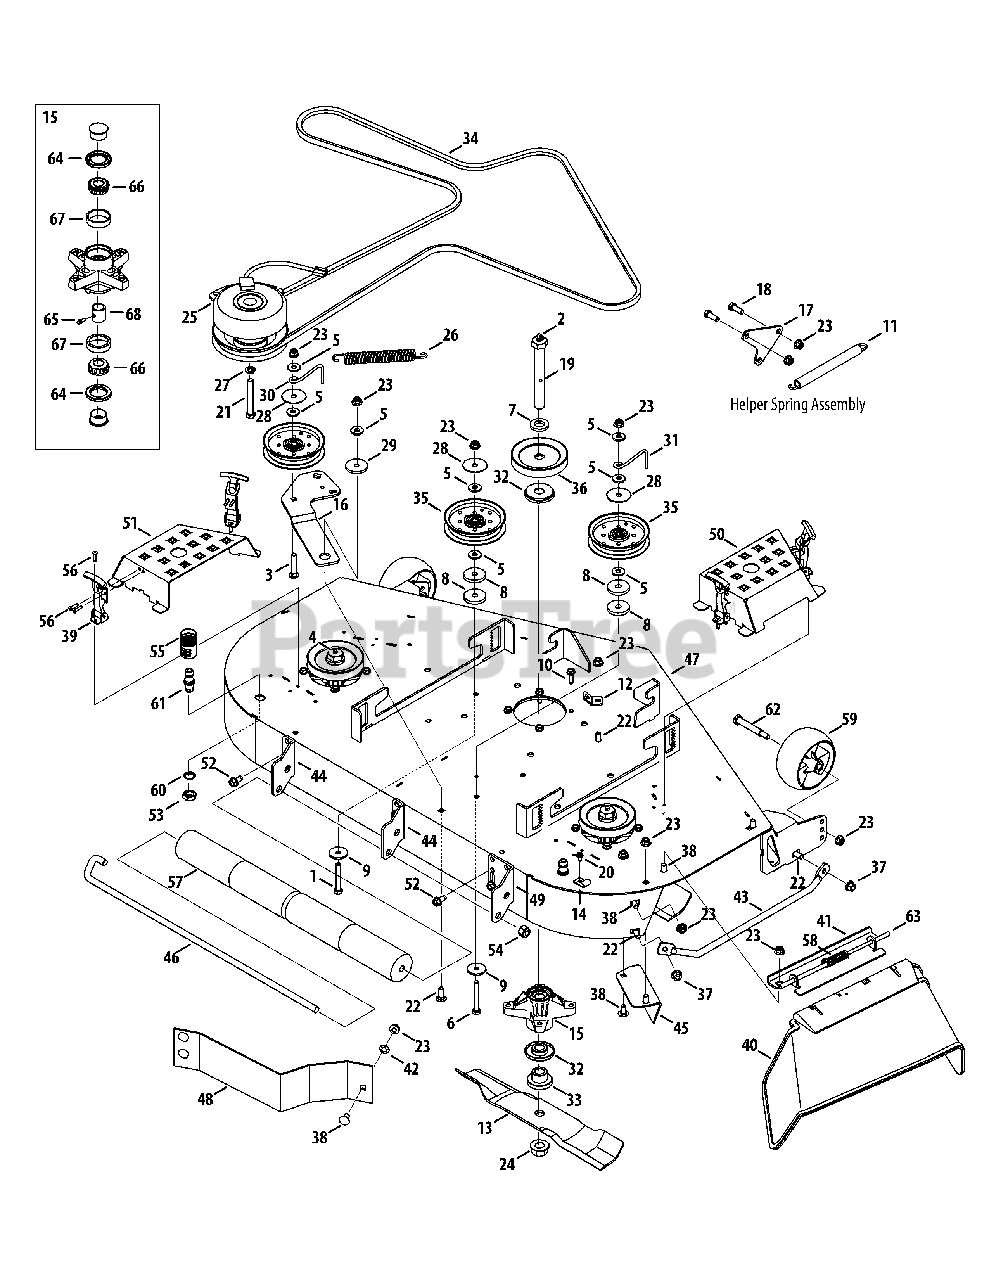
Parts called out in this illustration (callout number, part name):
1	Hex Screw, 3/8-16 x 2.50
2	Grease Fitting, 1/4-28 x .788
3	Carriage Bolt, 3/8-16 x 2.00
4	Straight Grease Fitting, 1/4-28
5	Washer, .406 x 1.00 x .105
6	Hex Screw, 3/8-16 x 2.75
7	Spacer, .812 x 1.47 x .218
8	Washer, .438 x 1.75 x .250
9	Washer, .390 x 1.50 x .122
10	Flange Hex TT Screw, 5/16-18 x 1.00
11	Hook Ext. Spring, .75 x 7.89 x .14
12	45-Degree Spring Mount Bracket
13	Blade, Hi-Lift, 17.0
14	Retainer Hook Bracket
15	Deck Spindle Assembly
18	Hex Screw, 3/8-16 x 1.00
19	Hex Screw, 3/4-16 x 6.00
20	Hex Washer TT Screw, 1/4-20 x .500
21	Hex Screw, 7/16-20 x 3.25
22	Carriage Bolt, 3/8-16 x 1.00
23	Flange Lock Nut, 3/8-16
24	Flange Lock Nut, 3/4-16
25	Electric PTO Clutch
26	Extension Spring, .91 x 7.33
27	Lock Washer, 7/16
28	Flat Washer, .406 x 1.92 x .060
29	Shoulder Spacer, .884 x .190
30	Belt Keeper Rod
31	Belt Keeper Rod
32	Deck Spindle Spacer
33	Spindle Spacer, .76 x 2.0 x 1.1
34	Hi-Performance Belt
35	Idler Pulley
36	V-Type Pulley
37	Counterlock Flange Nut, 3/8-16
38	Carriage Bolt, 3/8-16 x .75
39	T-Handle Latch Draw
40	Fab Deck Deflector Chute
41	Deflector Chute Bracket
42	Push Retainer Nut
43	Fab Deck Chute Finger Guard
44	Deck Roller Mount Bracket, Right
45	Micro Chute Baffle
46	J-Hook w/ Threaded Roller
47	48" Welded Deck
48	48" Standard Baffle
49	Deck Roller Mount Bracket
50	48" RH Belt Cover
51	48" LH Belt Cover
52	Screw TT, 3/8-16 x .75
53	Hex Nut, M16-1.5
54	Lock Nut, Nylon Insert, 1/2-13
55	Water Nozzle Adapter
56	Pop Rivet, .187 Dia.
57	Front Roller
58	Spring Torsion, 0.639 ID x 2.16 LG
59	Deck Wheel, 5.0
60	Lock Washer, 17 x 23.8 x 1.95
61	Water Deck Nozzle
62	Shoulder Bolt, 3/8-16 x .496 x 2.50
63	Chute Deflector Rod
65	Fitting, 3/16
66	Cone Bearing
67	Cup Bearing
68	Spacer, .78 x 1.0
